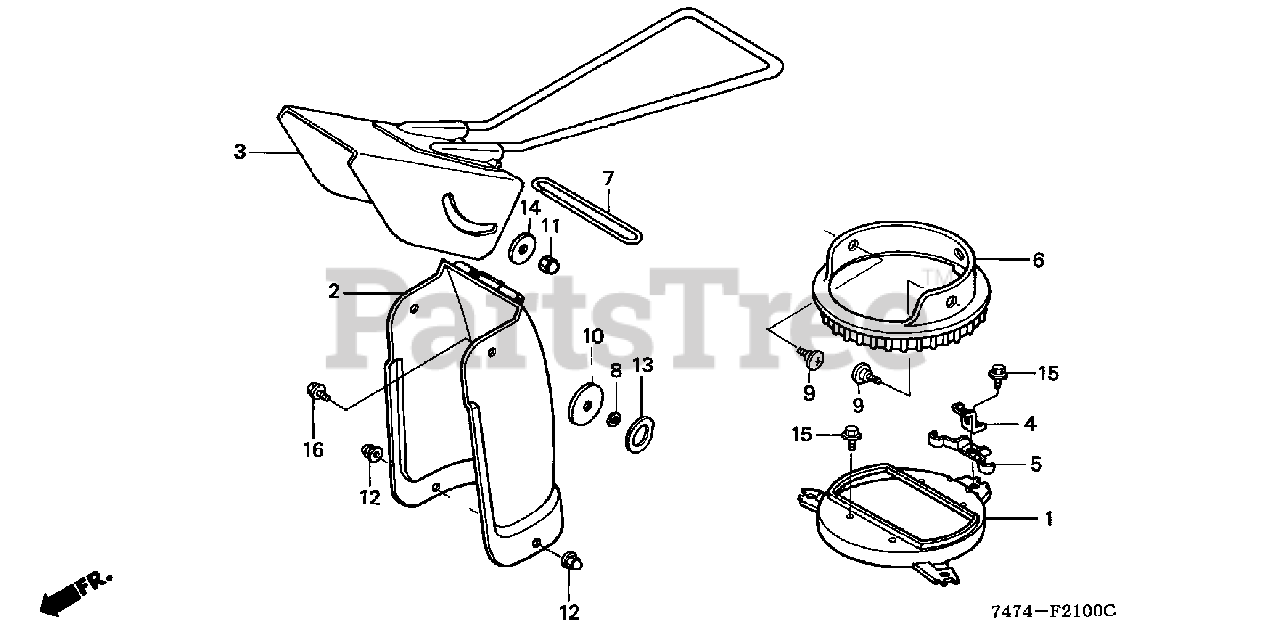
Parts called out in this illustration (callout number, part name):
1	RECEIVER, CHUTE
3	GUIDE, CHUTE
4	PLATE, CHUTE SETTING
5	SPRING, CHUTE SETTING
6	BUSH, CHUTE
7	PIN, CHUTE GUIDE
8	COLLAR, CHUTE GUIDE
9	BOLT, COVER SETTING
10	WASHER, TANK SETTING
11	NUT, CAP (6MM)
12	NUT, CAP (6MM) (BLACK)
13	WASHER, WAVE (13MM)
14	WASHER, TANK RUBBER
15	BOLT, FLANGE (6X10)
16	BOLT, FLANGE (6X16)
